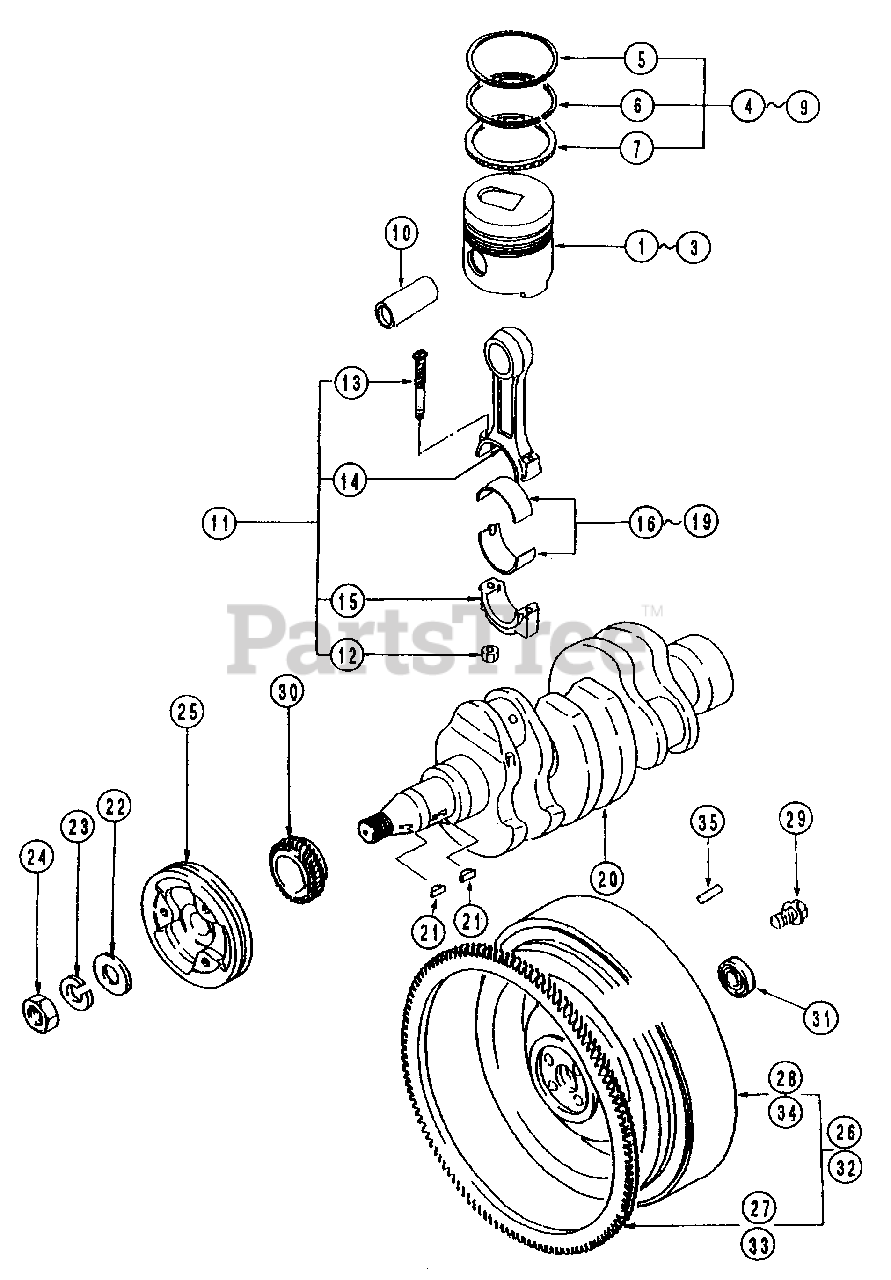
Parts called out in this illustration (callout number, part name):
2	Piston
3	Piston
4	Ring Set,Piston
7	Ring Ass'y.,Oil
8	Ring Set,Piston
9	Ring Set,Piston
10	Pin, Piston
11	Rod Ass'y.,Connecting
13	Bolt, Connecting
14	Con-Rod
15	Cap,Connecting Rod
16	Metal Set, Con-Rod
17	Metal Set, Con-Rod
18	Metal Set, Con-Rod
19	Metal Set, Con-Rod
21	Key, Woodruff
22	Washer, Plain
23	Washer, Spring
25	Pulley, Crankshaft
26	Flywheel Sub Ass'y
27	Gear,Ring
28	Flywheel
29	Bolt
30	Gear,Crankshaft
31	Bearing, Ball
32	Flywheel Sub Ass'y
34	Flywheel
35	Pin, Dowel
